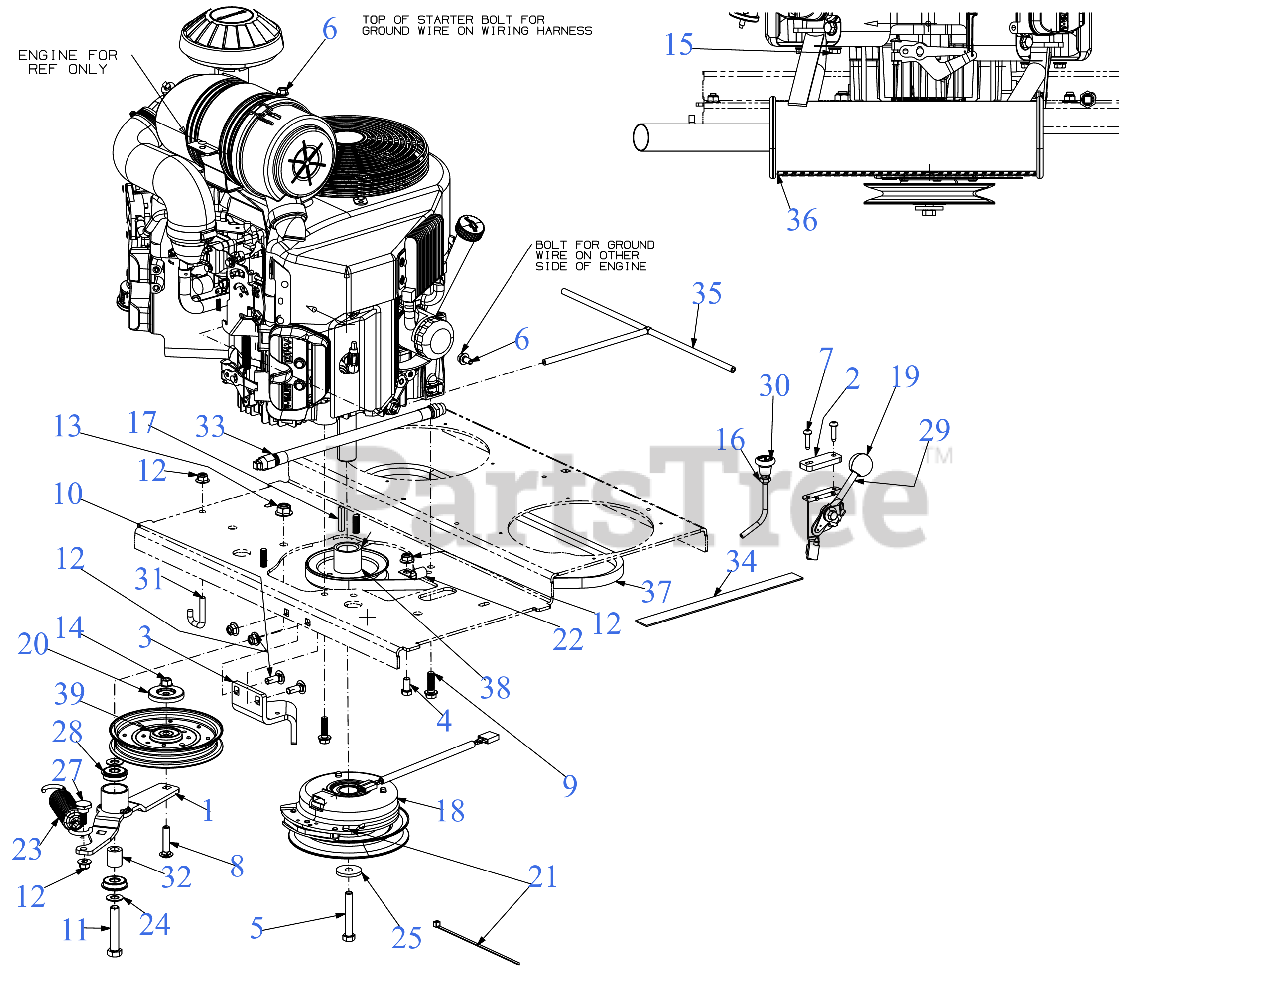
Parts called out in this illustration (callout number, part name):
1	TRANSMISSION IDLER BRACKET
3	CLUTCH RETAINER BRACKET
4	HEX SCREW 3/8-16 x .75
5	SCREW 7/16-20:2.75 GR5
6	SCREW M8 x 1.25 x 16MM GR8.8
7	SCREW 1/4-20 x 1.0
8	CARRIAGE BOLT 3/8-16 x 1.75 GR5
9	SCREW 3/8-16 x 1.25 GR5
10	CARRIAGE BOLT 3/8-16 x 1.00 GR5
11	SCREW 1/2-13 x 2.75 GR5
14	HEX LOCK NUT
15	HEX FLANGE NUT
16	HEX JAM NUT 3/8X24
17	SQUARE KEY 1/4 x 1.50
18	ELECTRIC PTO CLUTCH
20	PULLEY CAP
21	7" CABLE TIE
22	J TYPE CLIP
23	EXTENSION SPRING W/HOOK
24	FLAT WASHER .510X.995
25	FLAT WASHER .45 x 1.5 x .172 HT
27	SHOULDER SCREW .625 x .302 x 3/8-16
28	ROLLER BEARING .5X1.37X.44
29	THROTTLE CABLE 59"
30	CHOKE CABLE
31	ROD SPRING HOOK
32	SPACER 0.51 x 0.88 x 1.00
33	OIL DRAIN HOSE
34	HEAT SHIELD 24"
35	ROLLOVER VENT HOSE ASSEMBLY
36	KAWASAKI MUFFLER
37	TRANSMISSION BELT
38	PULLEY - PUMP DRIVE
39	IDLER PULLEY
